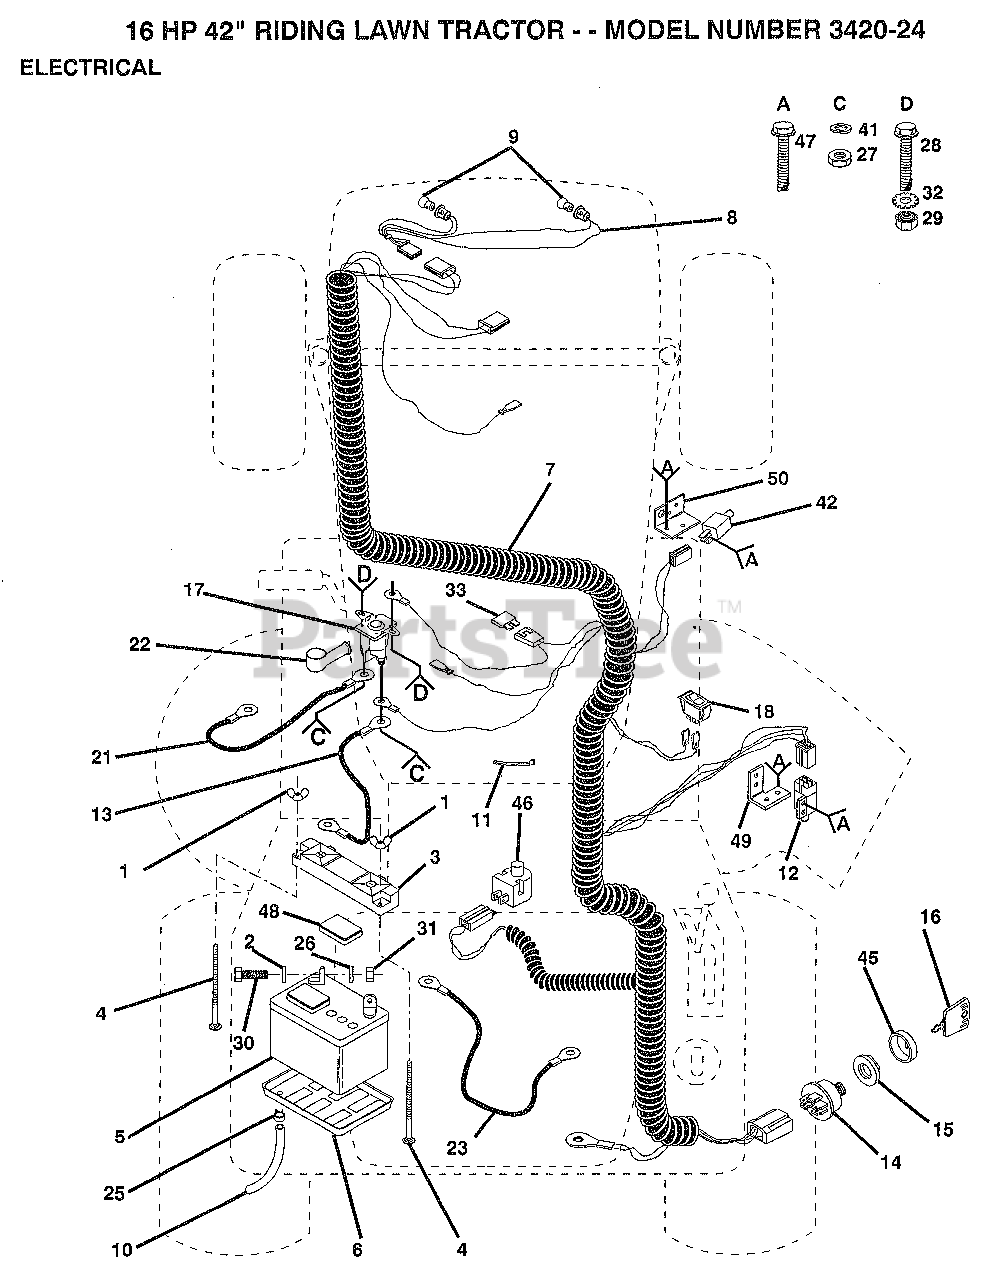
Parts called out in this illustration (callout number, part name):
2	WASHER
4	BOLT
6	"TRAY T, BATTERY"
7	"HARNESS,IGNITION"
11	WIRE TIE
12	SWITCH INTERLOCKT
13	CABLE-BATTERY T
15	NUT IGNITION
16	KEY
18	SWITCH LT
21	"CABLE T, BATTERY"
23	CABLE T
25	HOSE CLAMP T
26	LOCKWASHER
27	NUT
28	BOLT
29	NUT
33	FUSE HYT
42	SWITCH-INTER. GT
46	SWITCH SEAT
47	SCREW
48	"CAP,BATTERY "
